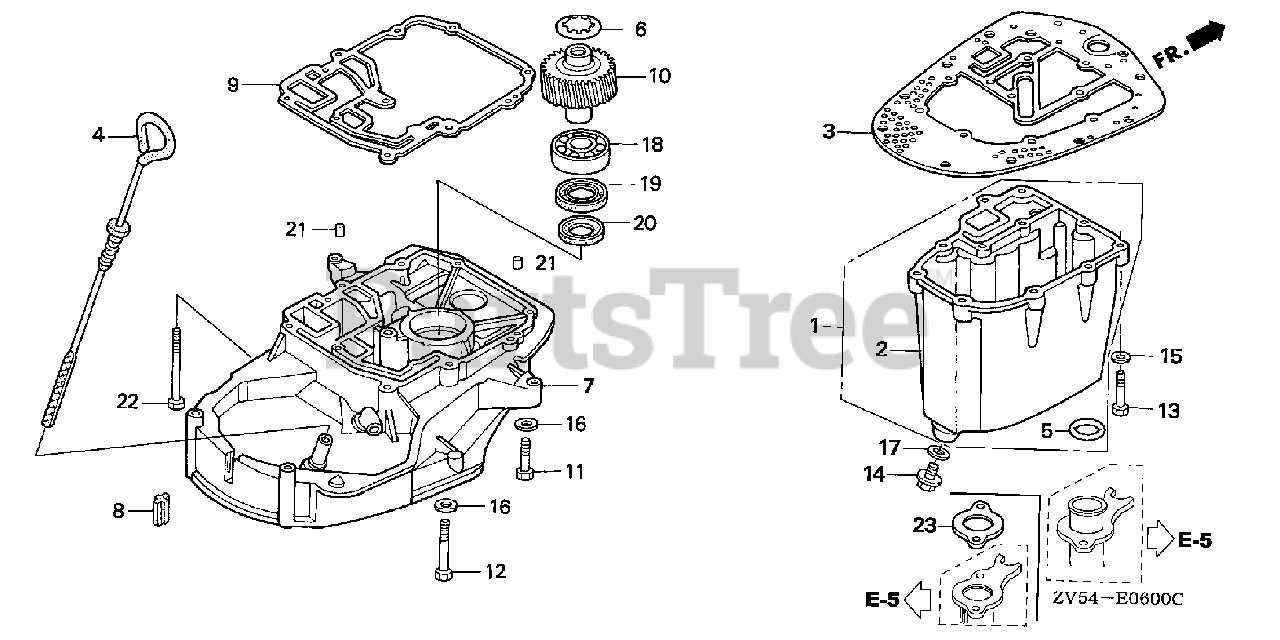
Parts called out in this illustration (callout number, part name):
1	OIL PAN KIT *TGRAY* (GRAY) (N/A: USE 04102-ZV5-000) (ALT. PNO: 04102-ZV5-000)
2	PAN, OIL *TGRAY* (GRAY)
3	GASKET, OIL PAN
4	DIPSTICK, OIL
5	GASKET, EX. PIPE
6	SPRING, THRUST
7	CASE, PRIMARY GEAR *NH8* (DARK GRAY)
8	RUBBER, SEAL
9	GASKET, PRIMARY GEAR CASE
10	GEAR, PRIMARY DRIVEN (33T)
11	BOLT, HEX. (8X35)
12	BOLT, HEX. (8X55)
13	BOLT, HEX. (6X25)
14	BOLT, DRAIN PLUG
15	WASHER, PLAIN (6MM)
16	WASHER, PLAIN (8MM)
17	WASHER, DRAIN PLUG (12MM)
18	BEARING, RADIAL BALL (6205)
19	OIL SEAL (25X40X7)
20	SEAL, WATER (17X26X7)
21	PIN, DOWEL (6X10)
22	BOLT, FLANGE (8X75)
23	GASKET, EX. PIPE
